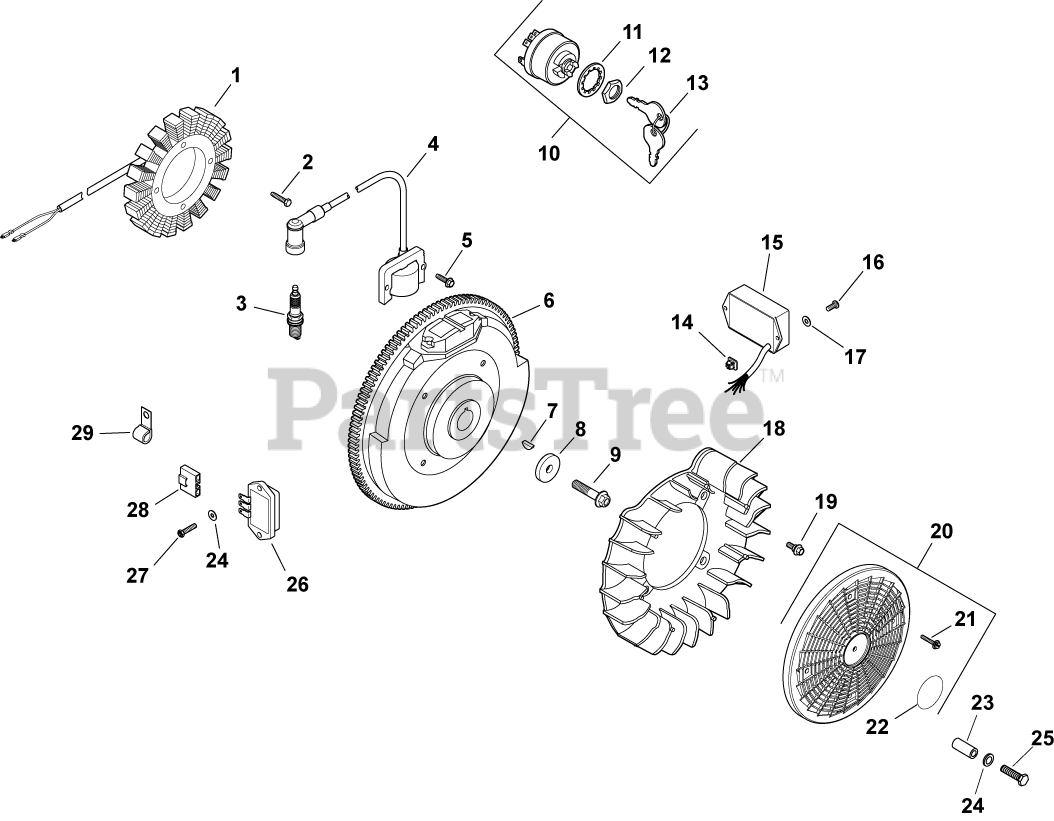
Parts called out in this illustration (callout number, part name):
1	KIT, 15 / 20 AMP STATOR
2	SCREW, M5X0.8X25 - (#25086402S)
3	PLUG, SPARK (STD)
4	MODULE, IGNITION
5	SCREW, SKT THD FRM M5X0.8X25
6	FLYWHEEL, PAINTED-USE 24 025 57-S
7	KEY, 3/16" X 5/8"
8	WASHER, FLAT 13/32"
9	SCREW, FLG M10X1.5X45 - (#25086361S)
10	SWITCH ASSY, KEY (KM)-USE 25 099 32-S
11	WASHER, INTERNAL TOOTH
12	NUT, KEY SWITCH
13	KEY, SET -USE 48 340 01-S
14	NUT, PLASTIC
15	MODULE, SPEED ADVANCE-DISCONTINUED SEE PB265
16	SCREW, PHL HD #11-16X1/2"
17	WASHER, FLAT 1/4" (O.D. 1/2")
18	FAN USE 24 157 11-S
19	BOLT, SHOULDER
20	KIT, GRASS SCREEN
21	SCREW, FLG SEMS M4X.7X25
22	DECAL, GRASS SCREEN USE 24 113 499-S
23	SPACER - DISCONTINUED
24	WASHER, FLAT 3/16"
25	SCREW, SLT HD CAP M4X0.7X25
26	REG/RECT-15 AMP (KM)-USE 41 403 10-S
27	SCREW, PHL HD #11-16X7/8"
28	CONNECTOR, BODY (KM)-USE 25 155 41-S
29	CLIP, CABLE
